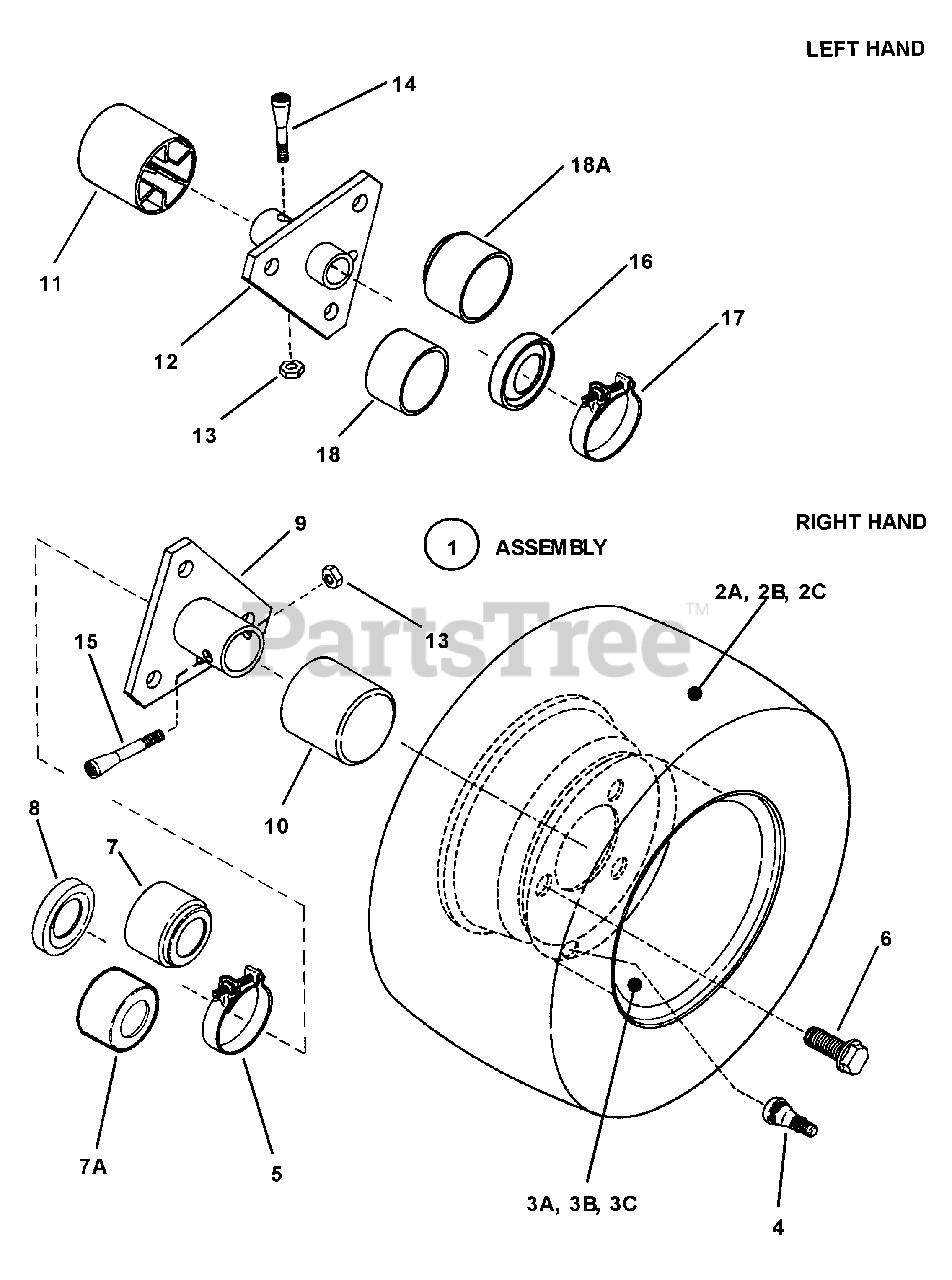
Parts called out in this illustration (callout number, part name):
1	ASSEMBLY, Rear Tire & Rim
2A	TIRE, Std., 16-4.80 x 8
2B	TIRE, Wide, 16-6.50 x 8
2C	TIRE, Extra Wide, 16-7.50 x 8
3A	RIM, Std.,
3B	RIM, Wide,
3C	RIM, Extra Wide,
4	VALVE, Air (Snap-in)
5	CLAMP, Right Hand
6	BOLT, 1/2-20 x 3/4" Lug
7	BOOT, Right Hand
7A	BOOT, Right Hand
8	SEAL, Oil
9	HUB, Rear Wheel R. H. (Weldment)
10	CAP, Hub
11	CAP, Hub (Left Hand)
12	HUB, Rear Wheel L.H. (Weldment)
13	NUT, 5/16-24 Hex Center Lock
14	BOLT, 5/16-24 x 1-5/8" Tapered (Left Hand)
15	BOLT, 5/16-24 x 2" Tapered (Right Hand)
16	SEAL, Oil (Left Hand)
17	CLAMP, (Left Hand)
18	BOOT, Ball Bearing Models (Left Hand)
18A	BOOT, Standard Models (Left Hand)
